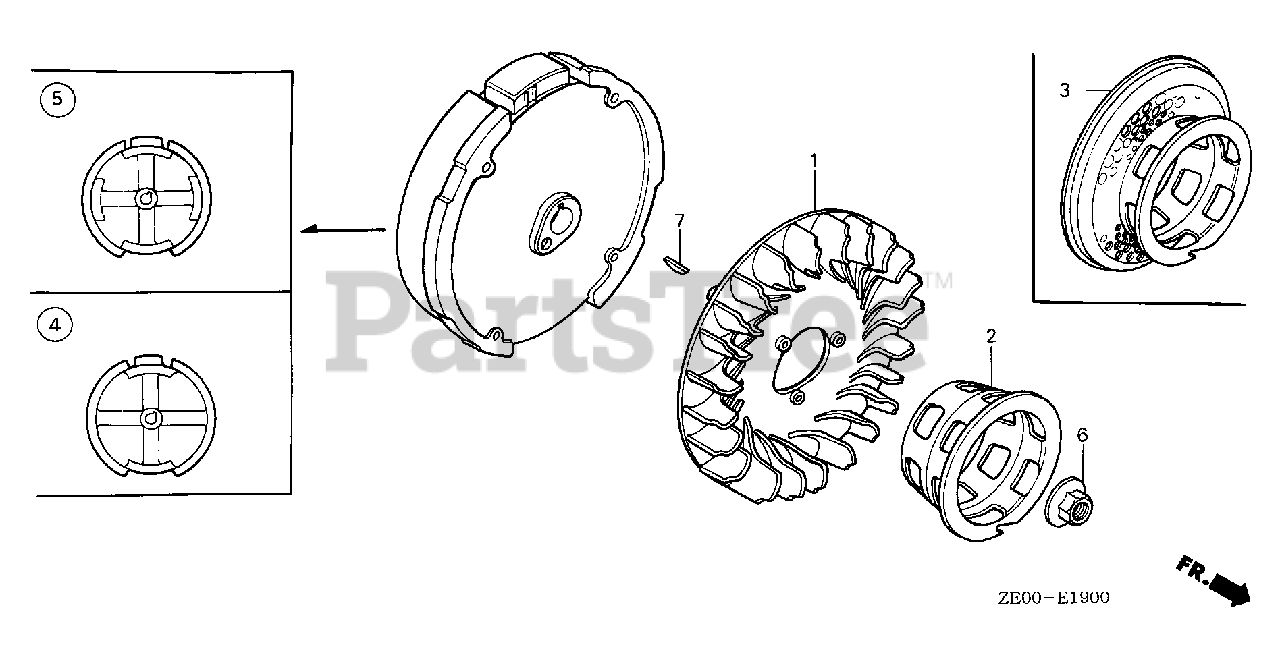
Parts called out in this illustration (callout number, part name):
1	FAN, COOLING
2	PULLEY, STARTER
6	NUT, SPECIAL (14MM)
7	KEY, SPECIAL WOODRUFF (25X18)
7	KEY, WOODRUFF (25X18)
